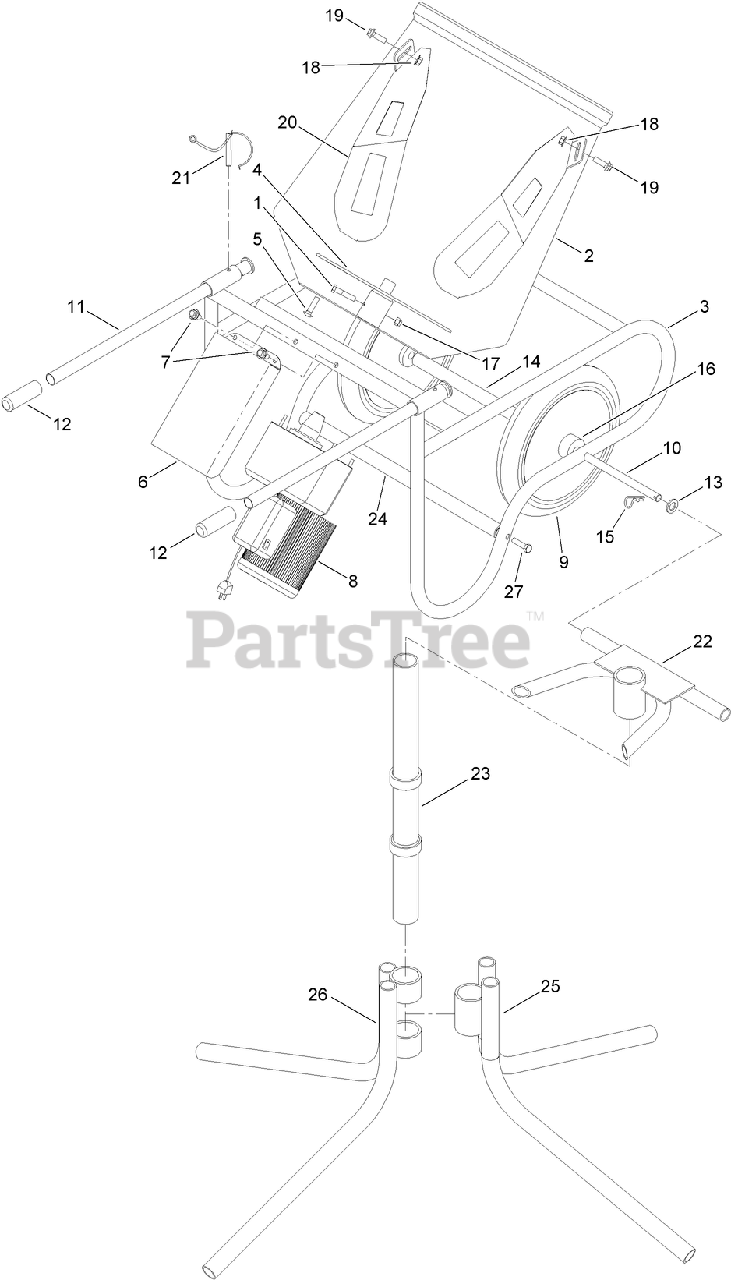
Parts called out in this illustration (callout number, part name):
2	DRUM-POLYETHYLENE
3	FRAME-WHEELBARROW
4	INSIDE PLATE ASM (W/ STRAIGHT BUSHING)
5	SCREW-HHF
6	COVER-MOTOR
7	SCREW-WHIZLOCK
8	GEAR MOTOR ASM
9	FLAT FREE WHEEL ASM
11	HANDLE-FRAME
12	GRIP-HANDLE
13	WASHER
14	SPACER-TUBE, AXLE
15	CLIP-R
16	BEARING-WHEEL
17	NUT-HHF, WHIZ
18	NUT-HF
19	SCREW-HHF
20	BLADE-MIXING
21	PIN-LOCKING (W/ LANYARDS)
22	BRACE-SUPPORT, TRI-POD STAND
23	SUPPORT-VERTICAL, TRI-POD STAND
24	BRACKET-HORIZONTAL, TRI-POD STAND
25	PIPE-SUPPORT, LEG 1 (TRI-POD STAND)
26	PIPE-SUPPORT, LEG 2 (TRI-POD STAND)
27	SCREW-HHF
